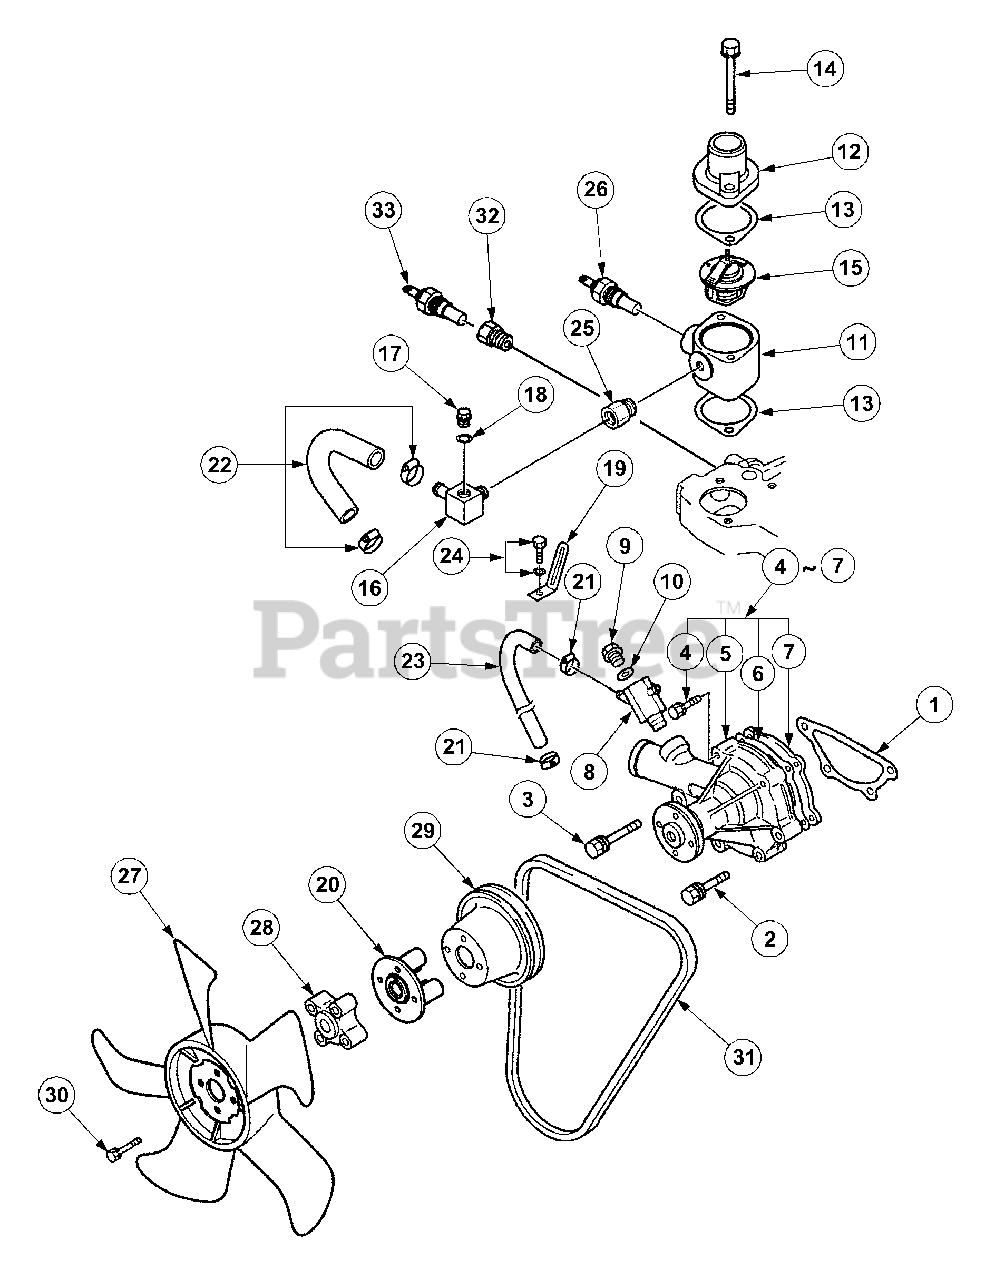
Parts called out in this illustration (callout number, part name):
2	Bolt,w/Washer
3	Bolt,w/Washer
4	Bolt,w/Washer
5	Body,Water Pump
6	Gasket,Water
7	Plate,Water
10	Gasket
11	Fitting,Thermo
12	Cover,Thermo
13	Gasket,Water
14	Bolt,w/Washer
15	Themostat
18	Gasket
22	Hose Assy,Water
24	Bolt,w/Washer
26	Switch,Thermo
27	Fan,Cooling
29	Pulley,Water
30	Bolt,w/Washer
32	Joint,Temp Gage
33	Gage,Unit Water
